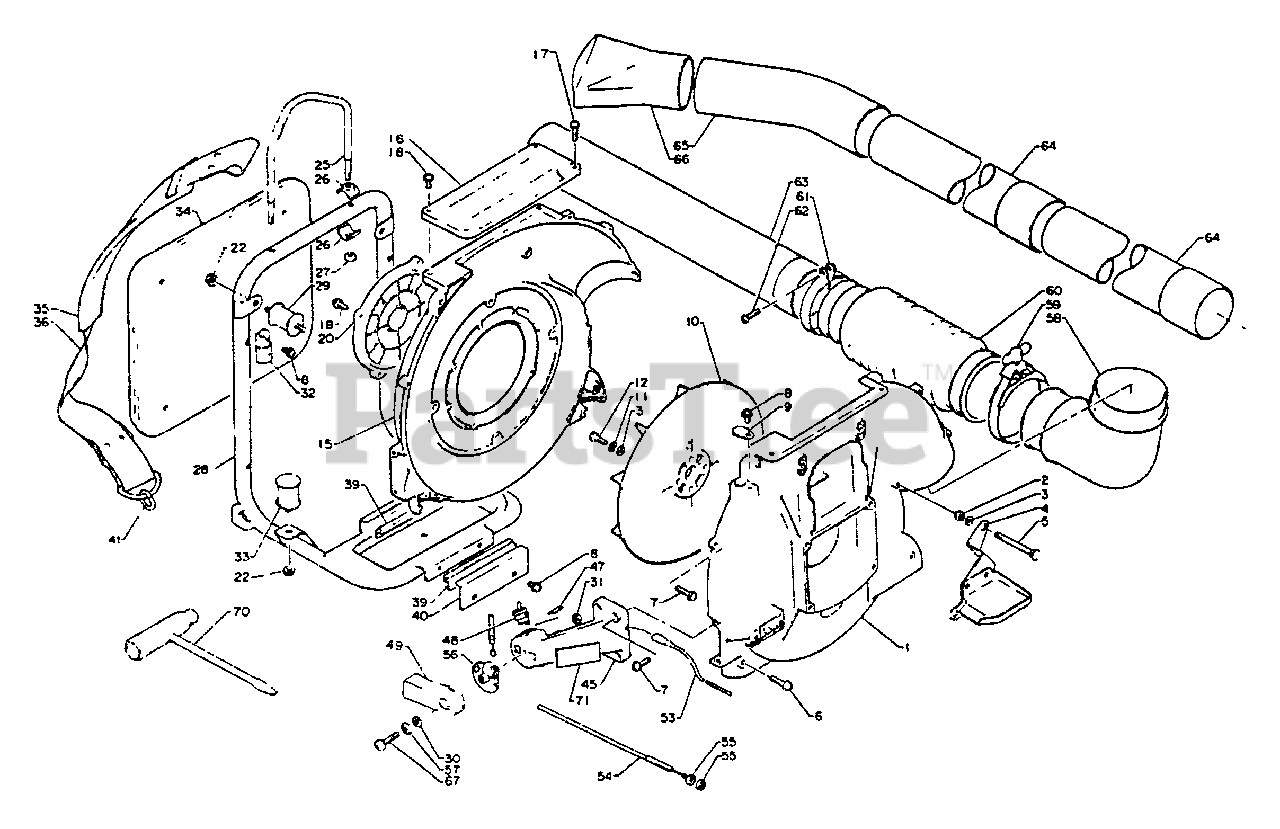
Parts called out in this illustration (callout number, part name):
1	COVER, FAN - OUTER
2	NUT - 5
3	WASHER, FLAT 5.5×10×0.8
4	BRACKET, MUFFLER COVER
6	SCREW 5×25
7	SCREW 5×20
8	SCREW 5×10
9	PLUG
11	WASHER, SPRING 5
12	BOLT - 5×16
15	COVER, FAN - INNER -- ORANGE
16	PLATE
17	SCREW 6×20
18	SCREW 6×15
20	SHIELD, DEBRIS
22	NUT, FLANGE M6
27	LOCKNUT - 6
28	FRAME, BACKPACK
30	WASHER 6.5×11.5×0.8
31	NUT, HEX M6
32	BRACKET, CUSHION
34	CUSHION
35	HARNESS
36	BACKPACK STRAP ASSY
39	CUSHION, FUEL TANK
40	BRACKET, FUEL TANK
41	RING, STRAP
45	MOUNT, THROTTLE LEVER
47	LABEL, ON-OFF
48	IGNITION SWITCH ASSY
49	CONTROL, THROTTLE
53	LEAD - GROUND
54	CABLE, THROTTLE
57	WASHER
60	TUBE, FLEXIBLE
61	CLAMP
62	SCREW 5×20
63	TUBE, BLOWER - STRAIGHT
64	TUBE, BLOWER - STRAIGHT
65	TUBE, BLOWER - CURVED
66	NOZZLE - FAN HEAD
67	SCREW 6×25
70	T-WRENCH 10×19 MM
71	LABEL - CAUTION
74	LABEL - ECHO
75	LABEL - NOISE
